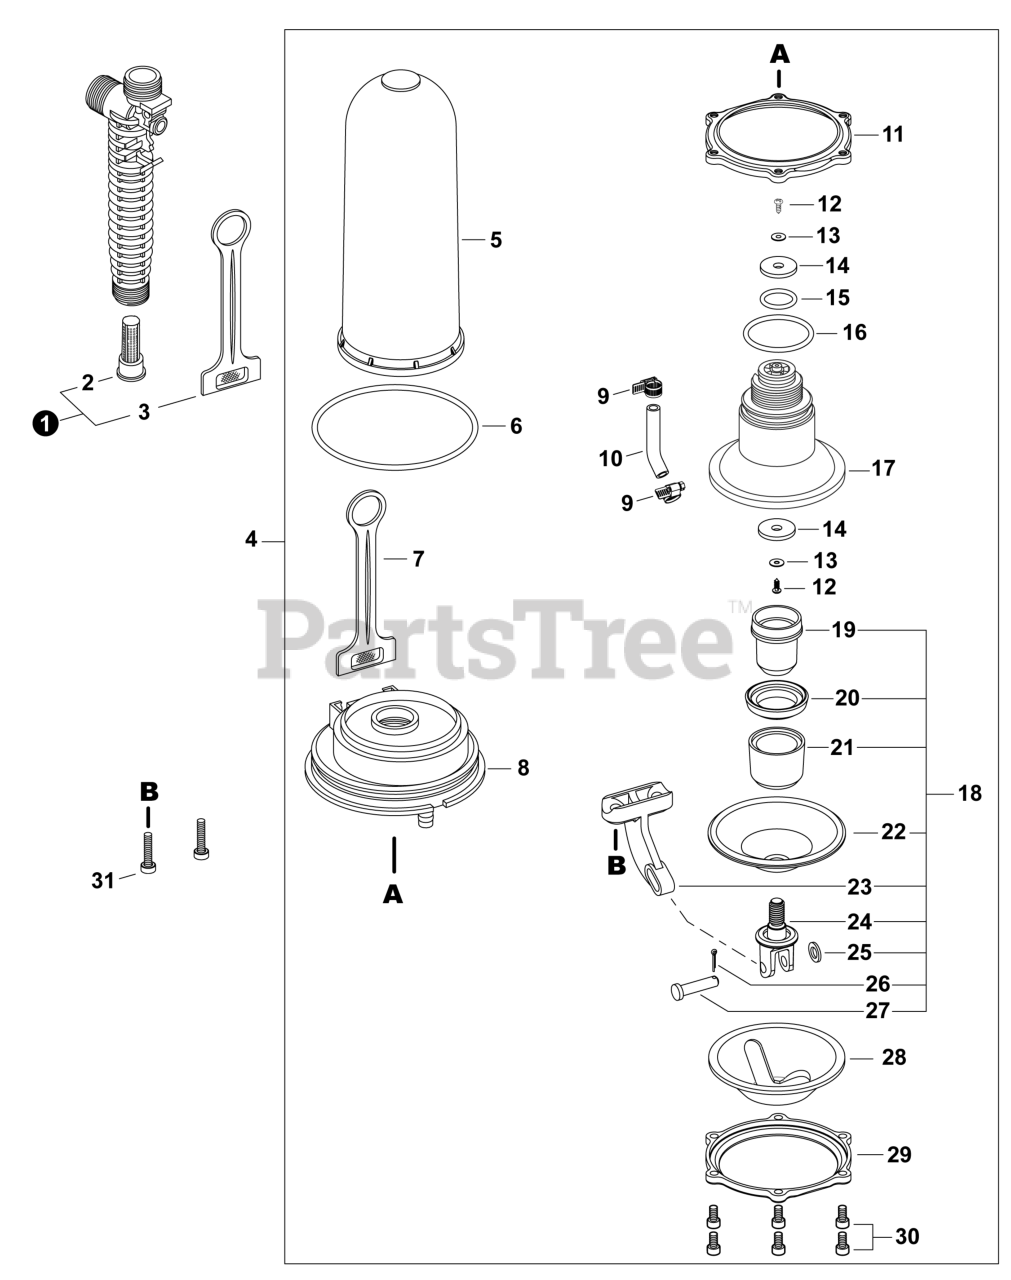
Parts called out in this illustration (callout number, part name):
1	FILTER KIT
2	FILTER, SPRAY GUN
3	FILTER, IN-TANK
4	PUMP ASSY, PISTON-DIAPHRAGM
5	CHAMBER, PRESSURE
6	O-RING, PRESSURE CHAMBER
7	FILTER, IN-TANK
8	BASE, PRESSURE CHAMBER
9	CLAMP, HOSE
10	TUBE
11	CLAMP, PUMP
12	SCREW, CYLINDER
13	WASHER, CYLINDER
14	SEAL, VALVE
15	O-RING, CYLINDER - SMALL
16	O-RING, CYLINDER - LARGE
17	PUMP, DIAPHRAGM
18	PISTON COLLAR ASSY
19	PISTON, INNER
20	SEAL
21	PISTON
22	DIAPHRAGM
23	LEVER, PIVOT
24	HINGE, PUMP
25	WASHER, LEVER
26	PIN, COTTER
27	PIN, LEVER
28	COVER, PUMP
29	CLAMP, PUMP
31	SCREW, LEVER
